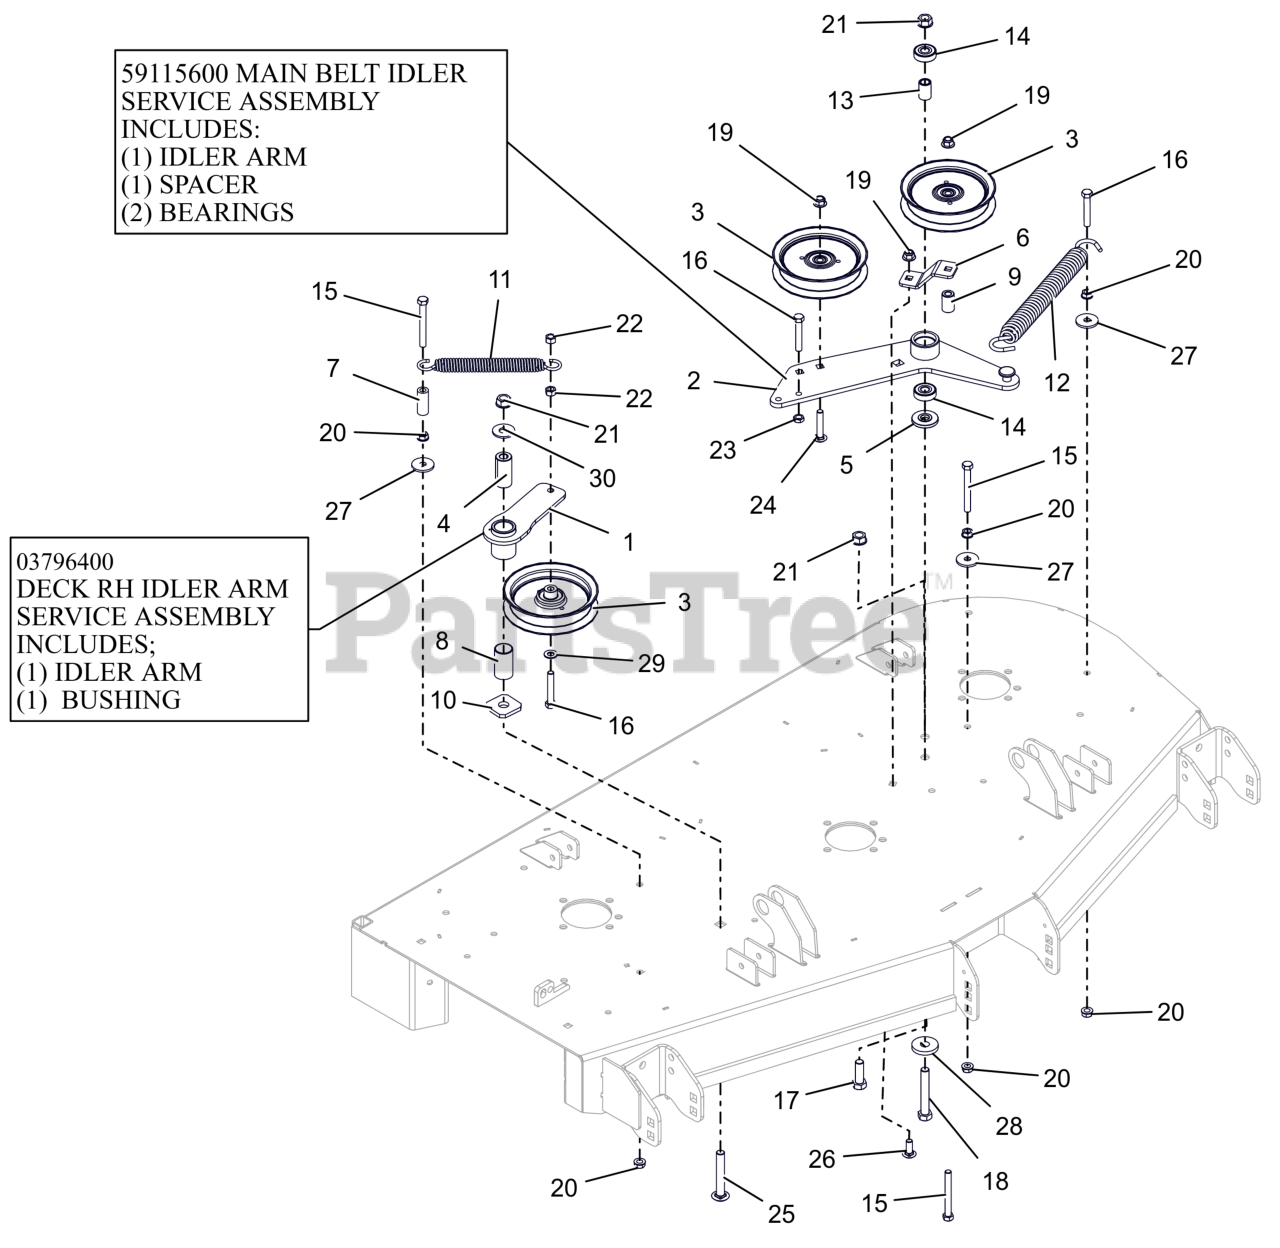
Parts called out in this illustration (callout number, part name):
1	WMT, IDLER ARM - BLACK
1	ASM, IDLER ARM (DECK)
2	WLDMT, DECK PTO IDLR ARM
2	ASSEMBLY, MAIN BELT IDLER
3	IDLER, FLAT 5.00"
4	BSHG, SPCR .502X.997X2.03 PM
5	SPACER, IDLER ARM
6	PTO FIXED IDLER MTG BRKT -RED
7	HOSE, .38 X 1.65
8	BSHG, 1.00X1.125X1.937
9	BUSHING, SLV .380X.750X1.190
10	WSHR-FLT .640X1.75X.250
11	SPRING, EXTENSION
12	SPRING, EXTENSION
13	SPACER .510 X .75 X 1.1485
14	BRG-BALL .500X1.38X.437
15	BLT, HEX .38-16X3.25 G5 ZCC
16	BLT,HEX .38-16X2.25 G5 ZCC
17	BLT,HEX .50-13X1.50 G5 ZCC
18	BLT,HEX .50-13X3.25 G5 ZCC
19	NUT,NYL-FLG .38-16 GF ZCC
20	NUT, SPNLK-FLG .38-16 G5 ZCC
21	NUT-LK-CTR-FLG .500-13 GG ZCC
22	NUT-LK-CTR .38-16 ZC120
23	NUT-JAM .375-16 G2 ZCC
24	BLT,RHSSN.375-16X2.00 G5 ZCC
25	BTL,RHSSN .500-13 X 3.25 G5 ZCC
26	BLT,RHSSN .38-16X1.00 G5 ZCC
27	WSHR,FLT .406X1.375X.135 ZCC
28	WSHR-FL-STL 0.557X1.625X0.25 ZCC
29	WSHR,FLT .406X.812X.065 ZCC
30	WSHR,FLT .563X1.375X.109 ZCC
